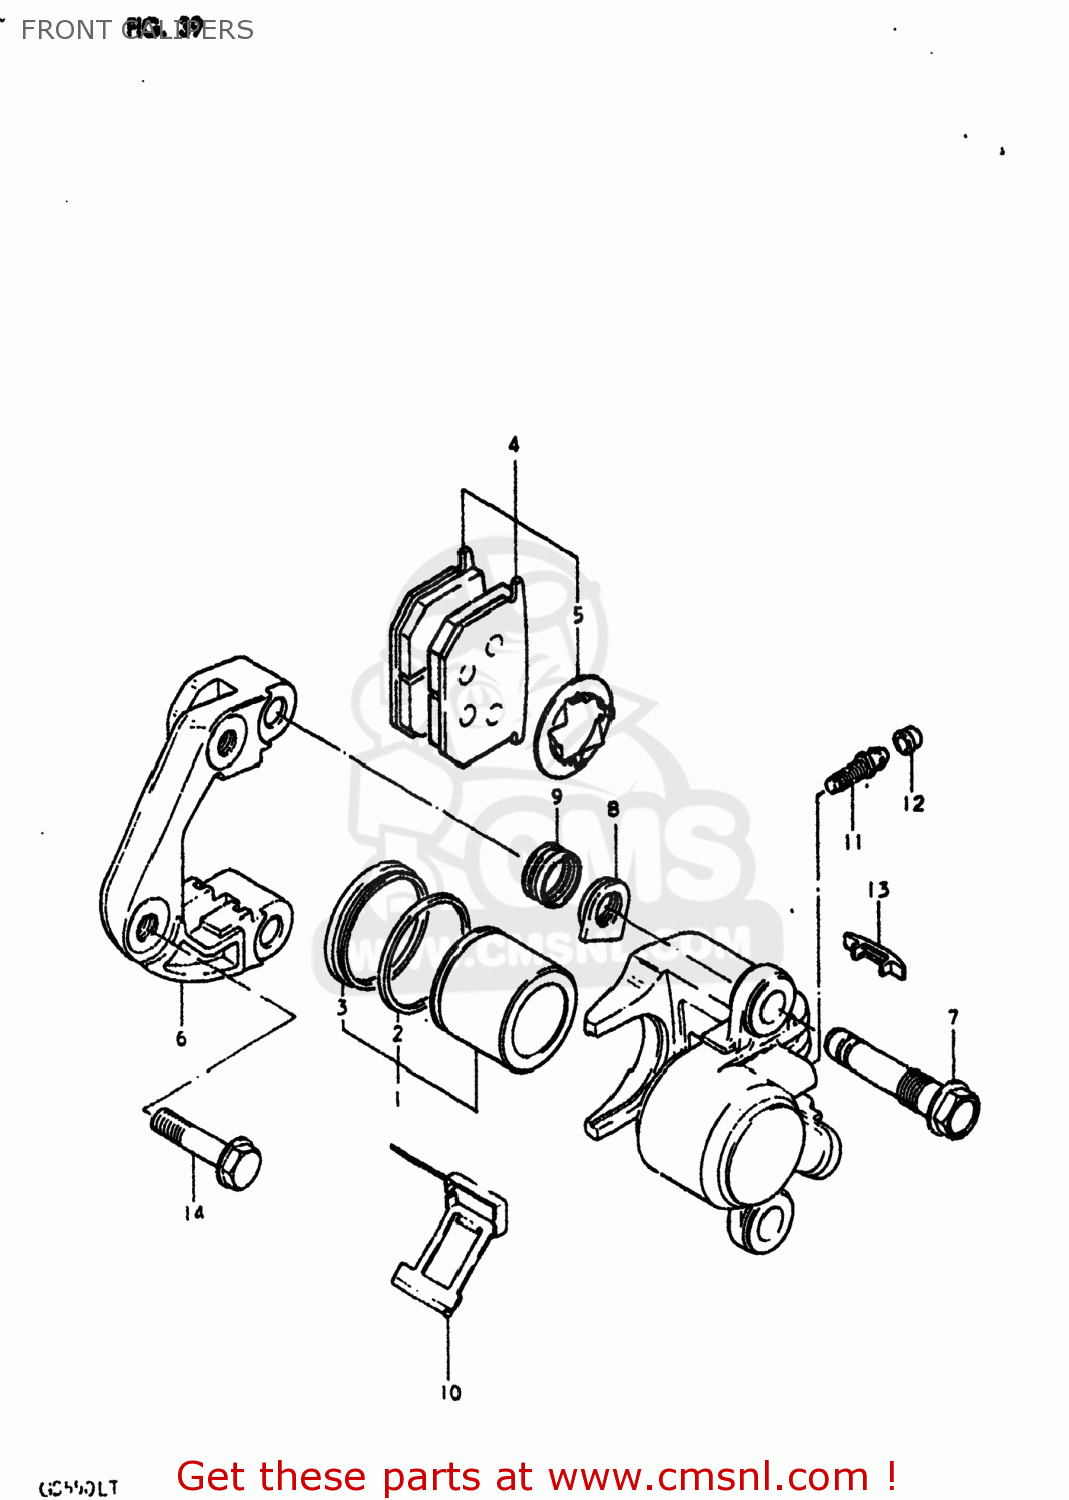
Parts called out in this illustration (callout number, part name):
1	PISTON SET
2	SEAL,PISTON
3	BOOT,PISTON
4	PAD & SHIM SET (MCA)
5	SHIM,PAD
6	BRACKET
7	AXLE,CALIPER
8	NUT,CALIPER AXLE
9	BOOT
10	SPRING
11	BREATHER
12	CAP,BLEEDER PL
13	COVER,INDICATOR
14	BOLT
